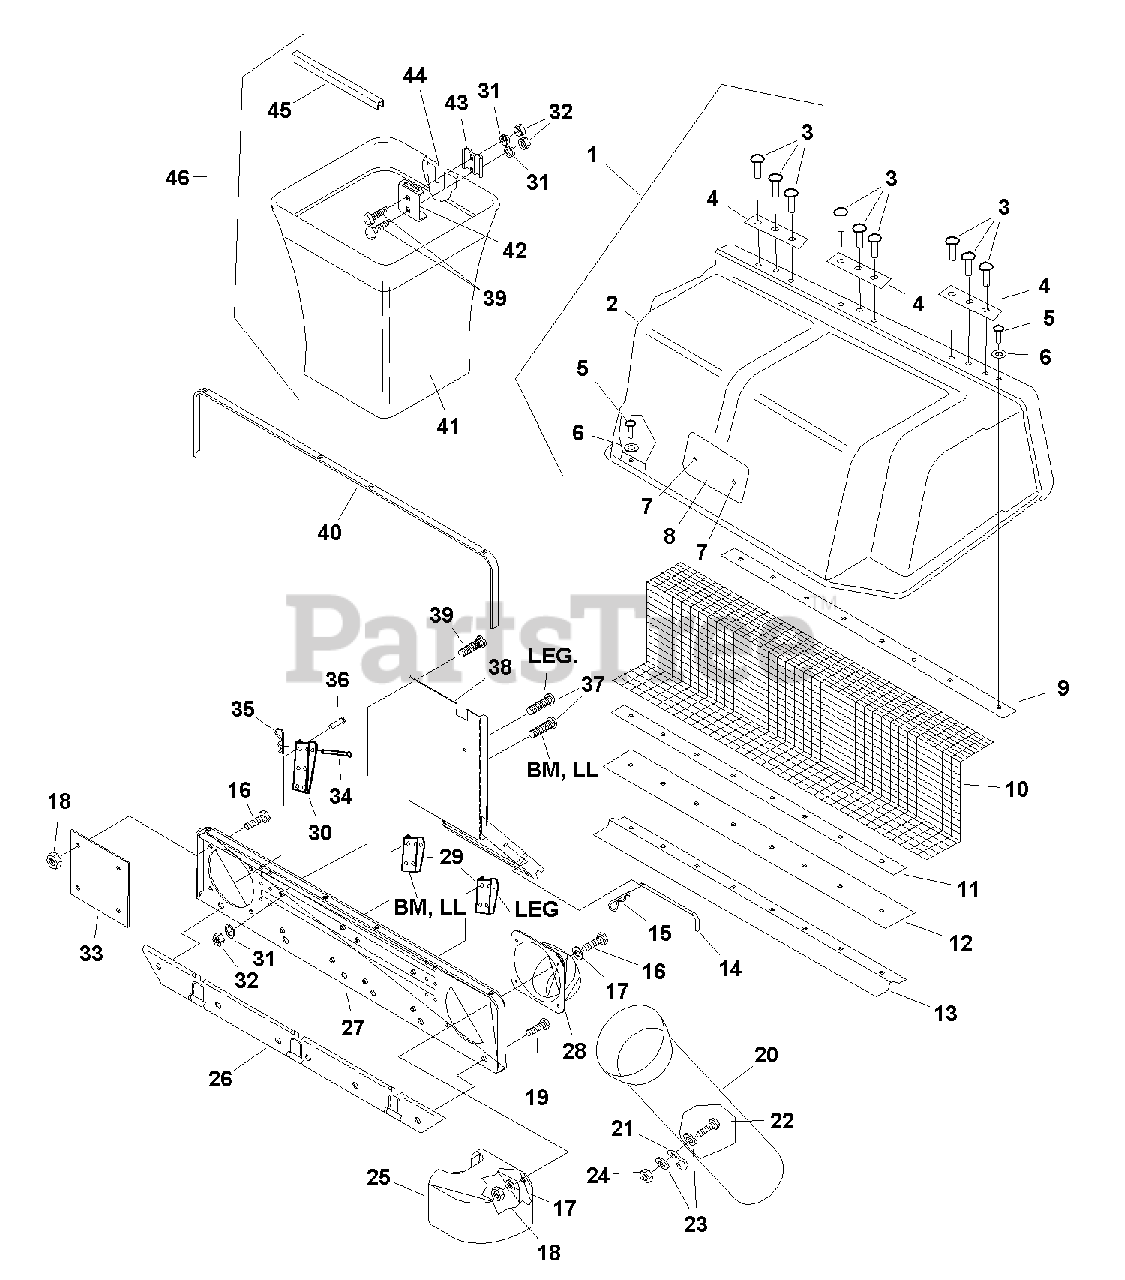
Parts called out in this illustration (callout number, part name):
1	COVER & SCREEN ASSEMBLY (Incl. Ref. Nos. 2,3,4,5,6,9,10,11,12,13)
4	PLATE ASSEMBLY
7	CLIP, Canoe
8	DECAL, Saftey
11	CLAMP, Seal
13	ANGLE, Screen
16	CAPSCREW, Hex Head, 5/16-18 x 1
17	WASHER, 5/16
18	LOCKNUT, 5/16-18
19	CAPSCREW, Taptite, 1/4-20 x 1/2
22	CAPSCREW, Hex Head, 1/4-20 x 1-1/4
23	WASHER, 1/4
24	LOCKNUT, 1/4-20
26	BRACKET ASSEMBLY
27	PLATE ASSEMBLY
31	LOCKWASHER, 5/16
32	NUT, 5/16-18
34	PIN, 3/8 x 2-3/4
35	PIN, Hair
36	RIVET
37	CARRIAGE BOLT, 5/16-18 x 1-1/4
38	SUPPORT ASSEMBLY
39	CARRIAGE BOLT, 5/16-18 x 3/4
44	HOOP, Basket Frame
46	GRASS BAG & HOOP ASSEMBLY (Incl. Ref. Nos. 31, 32, 39, 42, 43, 44 & 45)
